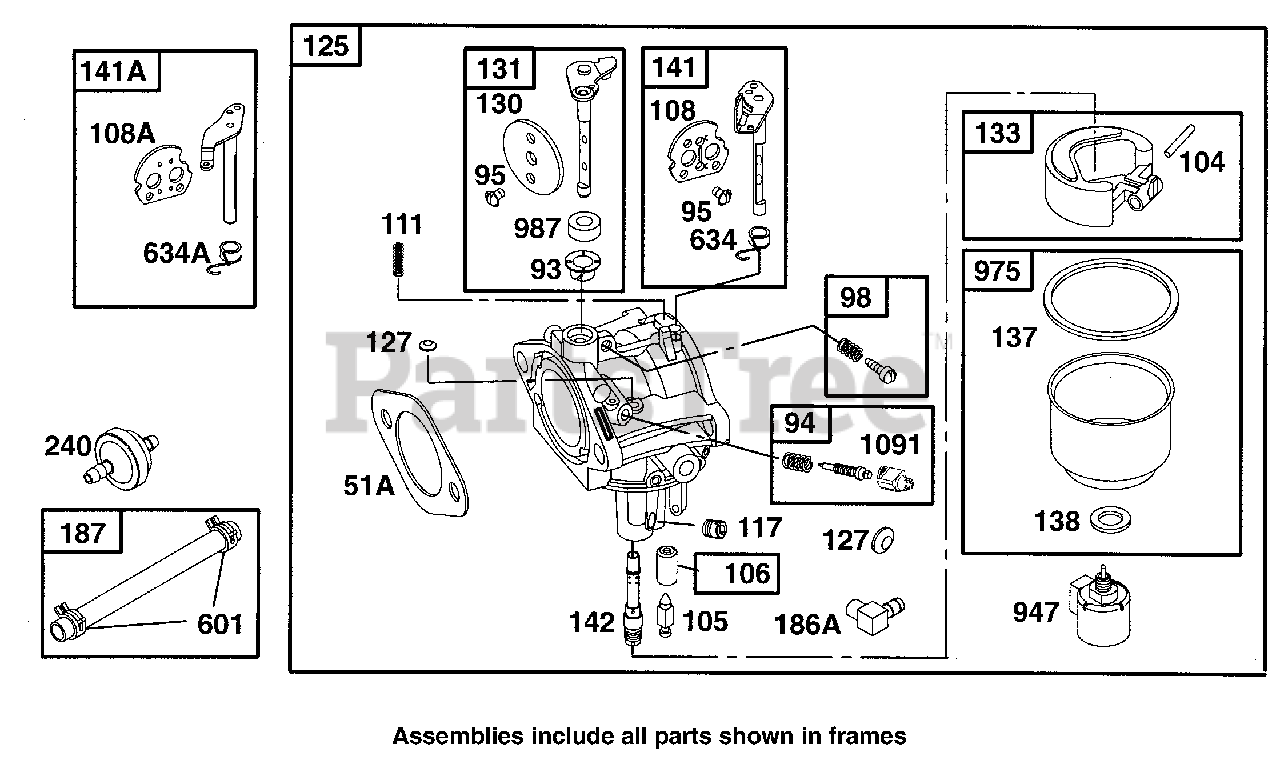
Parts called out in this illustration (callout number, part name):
51A	Intake Gasket
93	Throttle Shaft Bushing
94	Idle Mixture Kit
95	Choke Throttle Screw
104	Float Hinge Pin
105	Float Needle Valve
106	Inlet Seat (Pump Feed)
108	Choke Valve (Manual Choke)
108A	Choke Valve (Choke-A-Matic)
111	Detent Spring
117	Main Jet (Standard)
125	Carburetor
127	Welch Plug
130	Throttle Valve
131	Throttle Shaft Kit
133	Carburetor Float
137	Float Bowl Gasket
138	Seal Washer
141	Choke Shaft Kit (Manual Choke)
141A	Choke Shaft Kit (Choke-A-Matic)
142	Carburetor Nozzle
186A	Hose Connector
634	Spring Assembly Seal (Manual Choke)
634A	Spring Assembly Seal (Choke-A-Matic)
947	Fuel Solenoid
975	Float Bowl
987	Throttle Shaft Seal
1091	Limiter Cap
